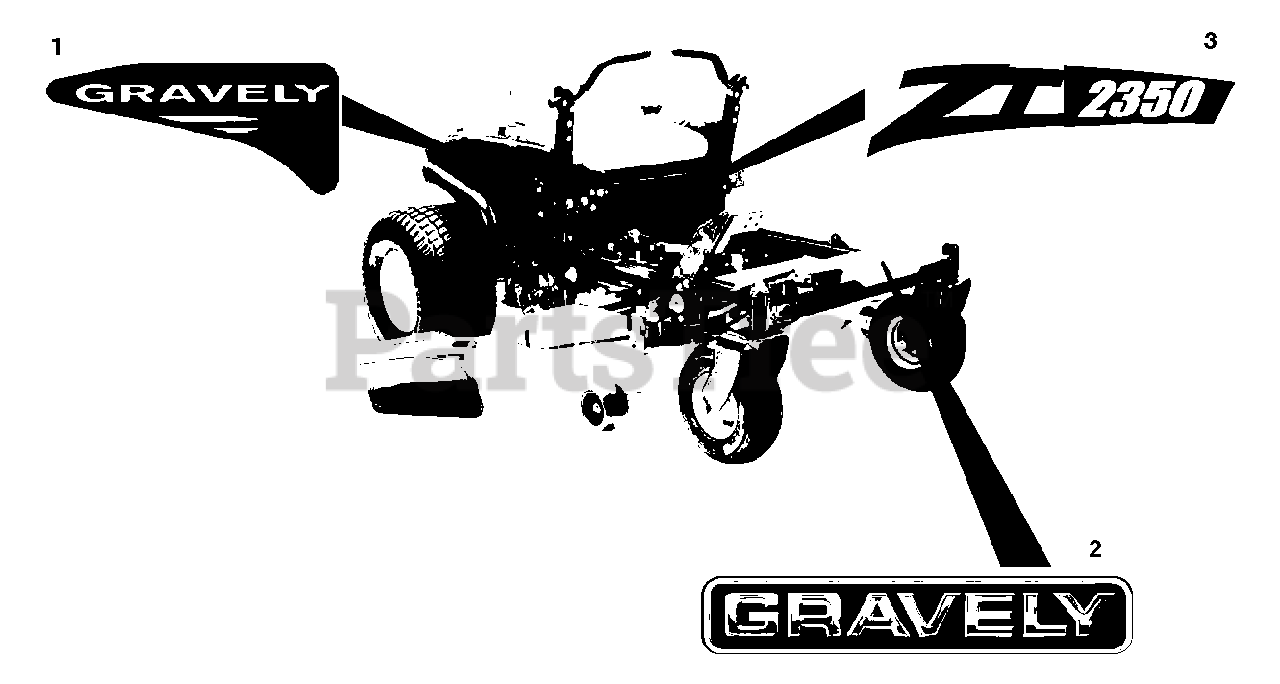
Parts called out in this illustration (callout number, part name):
1	Decal, Gravely ZT RH Fender
2	Decal, Gravely Logo
3	Decal, Gravely 1734 ZT (100)
